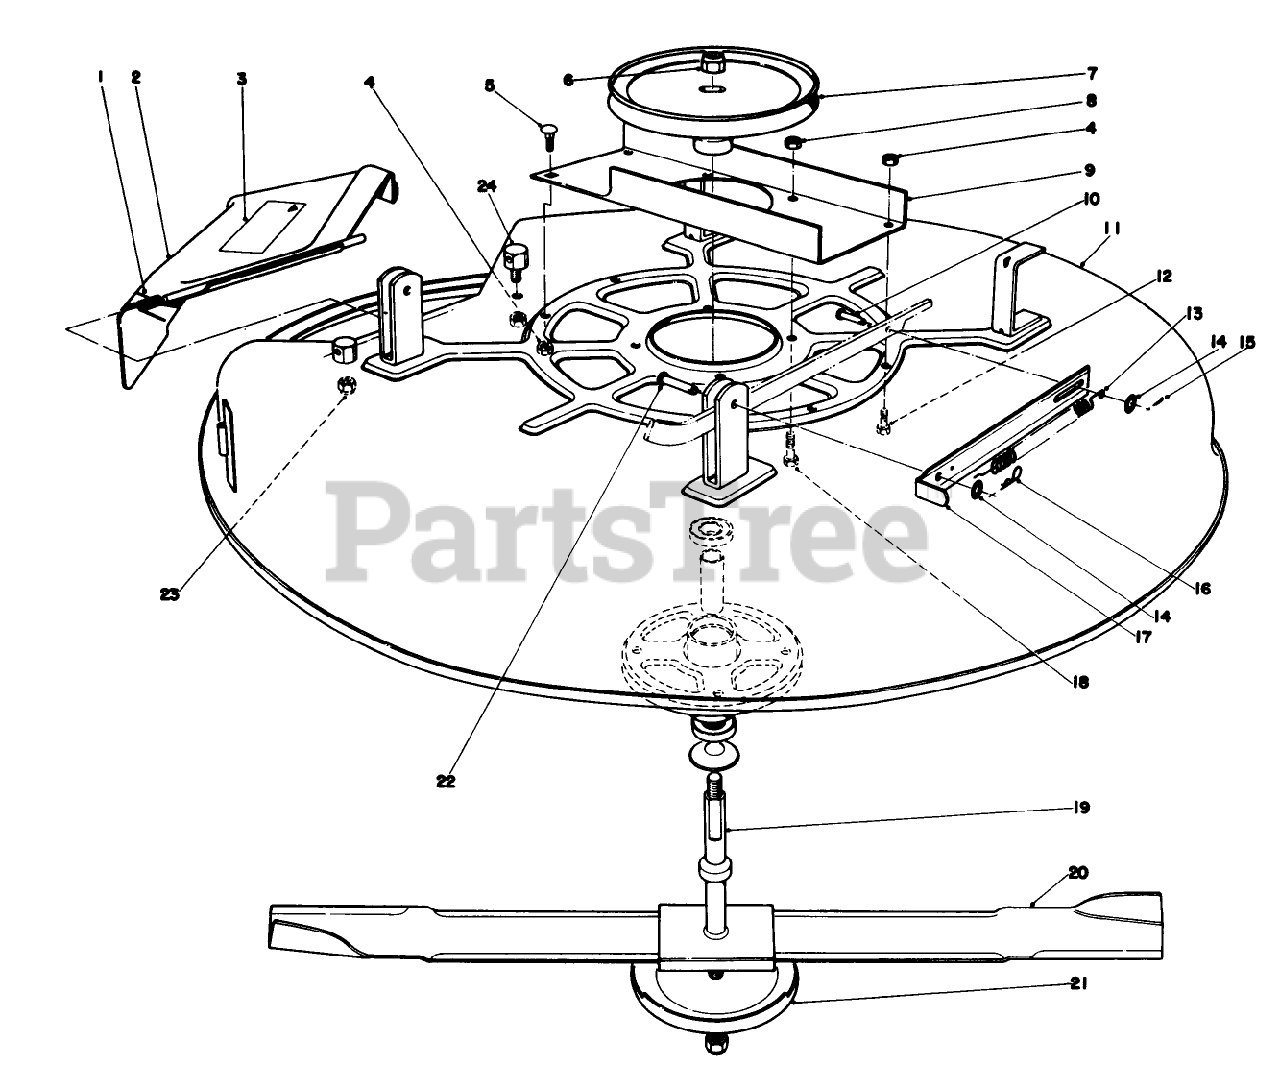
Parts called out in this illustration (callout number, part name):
1	SPRING
4	NUT-HEX, SIDE DEFORM
5	SCREW-CARR
6	NUT-SPECIAL
8	NUT-LOCK, CONE
10	PIN-CLEVIS
12	SCREW-HH
14	WASHER-FLAT
15	PIN-COTTER
16	PIN-COTTER
18	SCREW-HH
22	PIN-CLEVIS
23	NUT-LOCK, SIDE
24	POST-PIVOT
